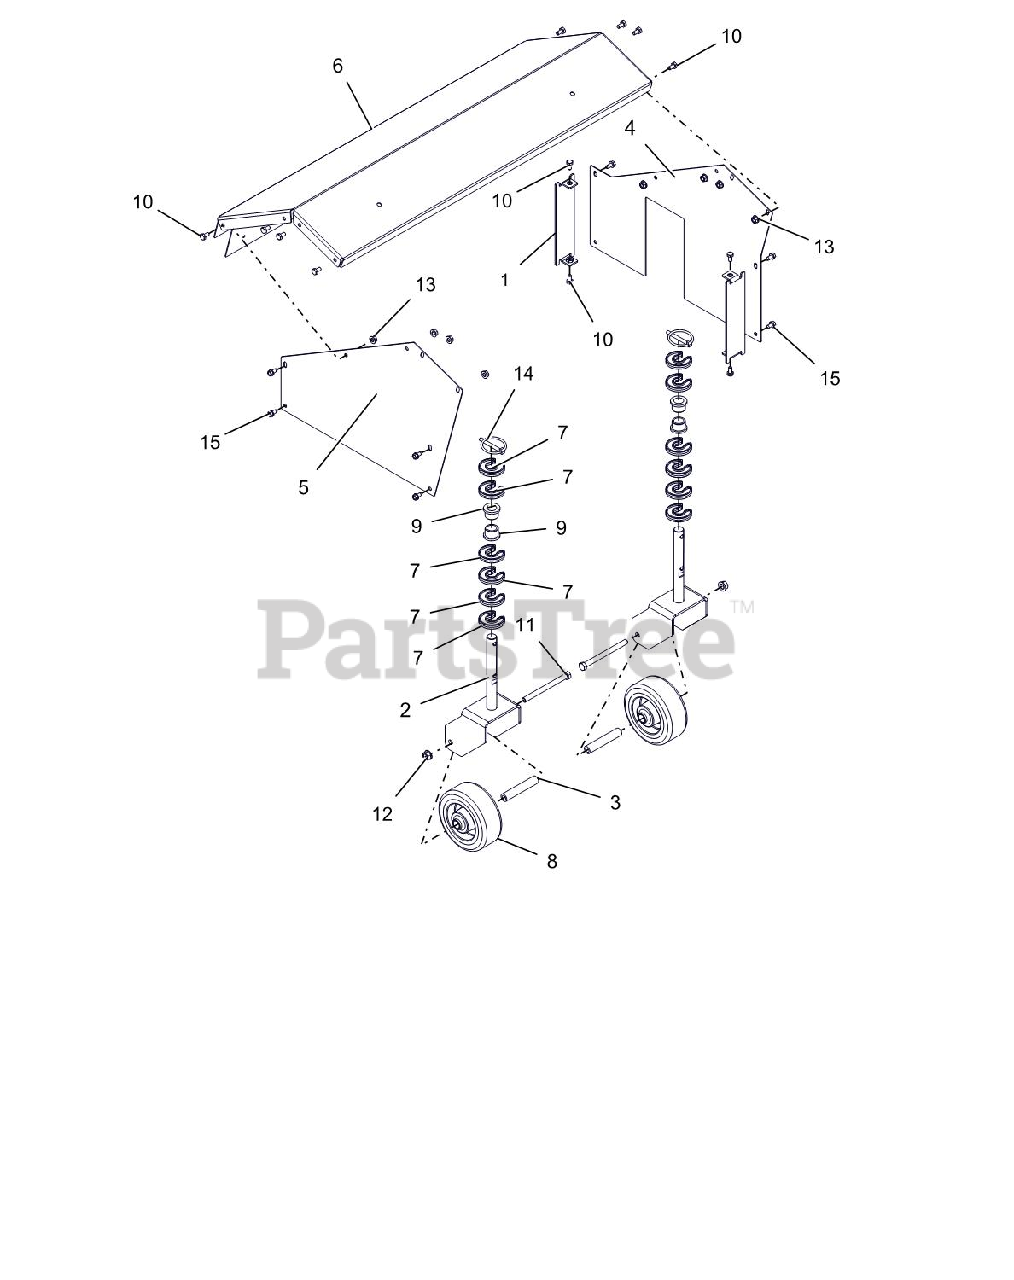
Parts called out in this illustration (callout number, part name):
1	COVER,END
2	FORK, CASTER-BRUSH
3	SPACER, CASTER WHEEL
4	COVER,LH SIDE BRUSH
5	COVER,RH SIDE BRUSH
6	COVER WITH DECALS, 28"BRUSH
7	CLIP-HOC FIXED
8	WHEEL, CASTER - 5"OD
9	BUSHING, FLANGE .75X.75X1.0
10	@BLT-HEX .25-20X.50 GR5 YWZC
11	@BLT-HEX .38-16X4.50 GR5 YWZC
12	@NUT-LK-TOP-FLG .38-16 YWZC
13	@NUT-LK-TOP-FLG .25-20 YWZC
14	PIN, LYNCH - .25 X 1.25
15	SCR-TAP .25-20X.50 HWH TR YWZ
